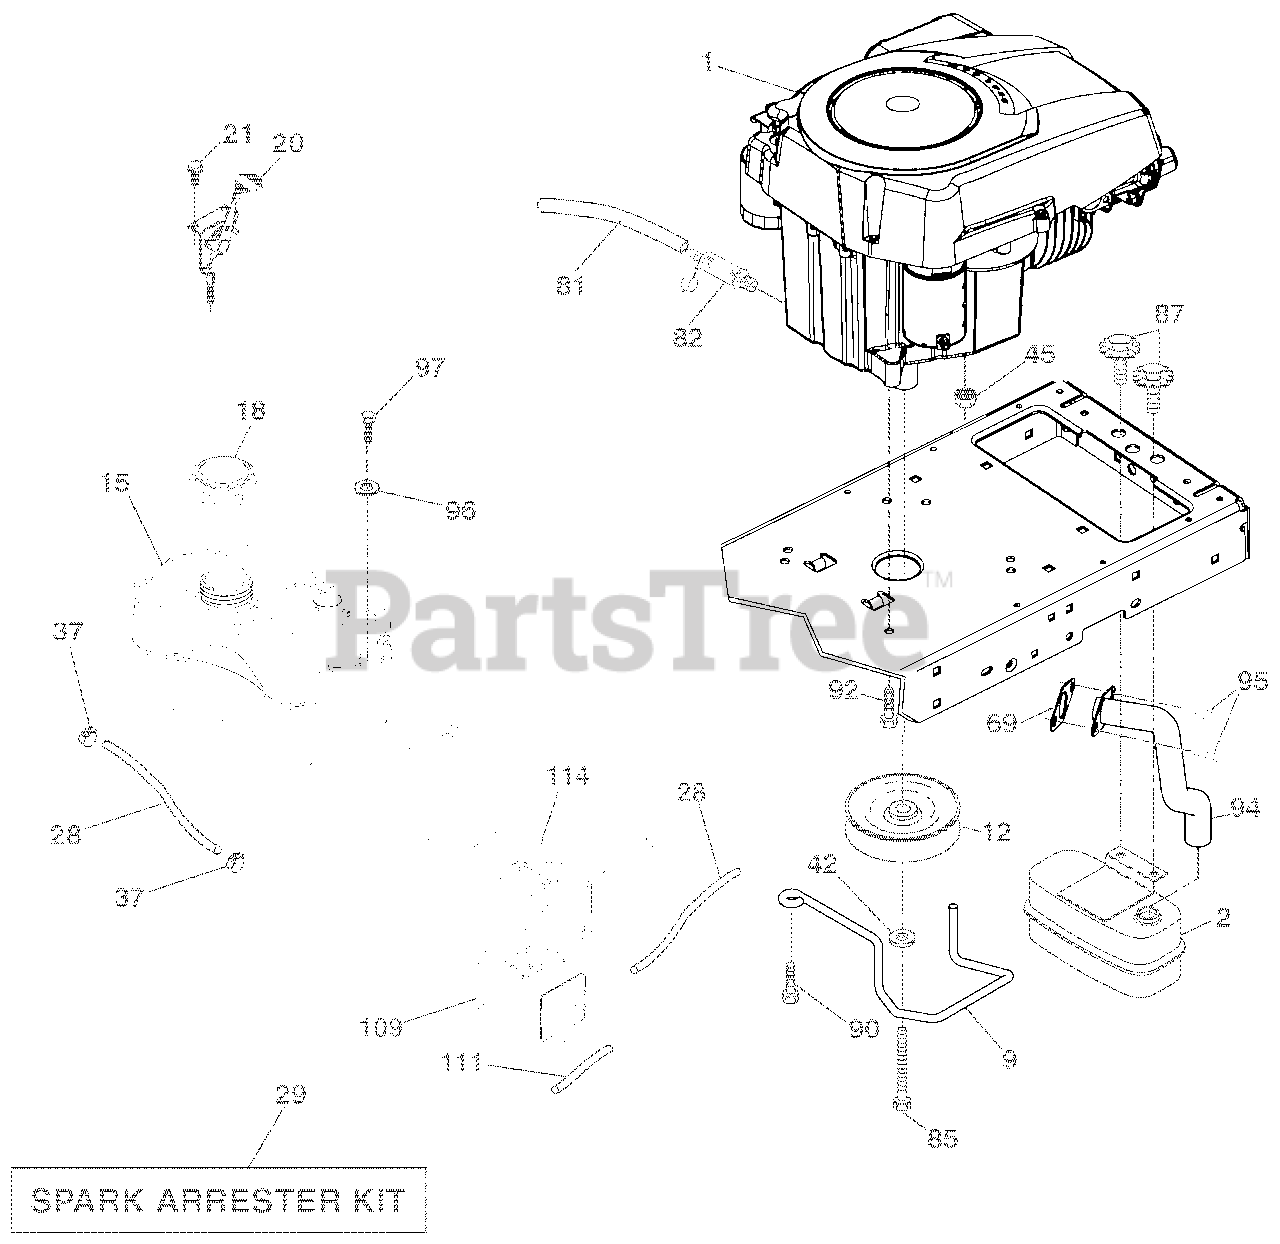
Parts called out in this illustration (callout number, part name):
2	MUFFLER.SINGLE.CYL.KOHL.COURAG
9	KEEPER.BELT.ENGINE.3.25"NSTL
12	PULLEY.ENGINE
15	TANK ASM.FUEL.1.50.CARB.CA.SVC
18	CAP ASM.FUEL.TETHER
20	CONTROL.TH/CK.COBRA.BS.EEC.428
28	LINE.FUEL.22"FRONT.EMIS.CA.LP
29	KIT.SPARK ARRESTOR(392390 B&S)
37	CLAMP.HOSE.BLK.
42	WASHER.LOCK.HVY HLCL.SPR.7/16
45	Nut, Keps Hex 1/4-20 unc
69	GASKET.KOHLER.SV.I.
81	TUBE.DRAIN.OIL.EASY
82	PLUG.DRAIN.OIL.EASY
85	BOLT.HEX.7/16-20X4XGR5-1.5THR.
87	BOLT.5/16-18UNCX3/4 W/SEMS.BLK
90	SCREW.3/8-16X1.SMGML.TAP/R.BLK
92	SCREW.3/8-16 X 1.SMGML.TAP/R
94	TUBE.EXHAUST.KOHL.COURAGE
95	SCREW.SOCKET HD.5/16-18 X .75
96	WASHER.9/32 X 7/8 X 16GA.
97	SCREW.HEXWSH.THDROL.1/4-20X3/4
109	CANISTER.CARBON.FILTER ASM.TEX
111	PURGE.LINE.CARB
114	CRADLE.CANISTER.CARBON
